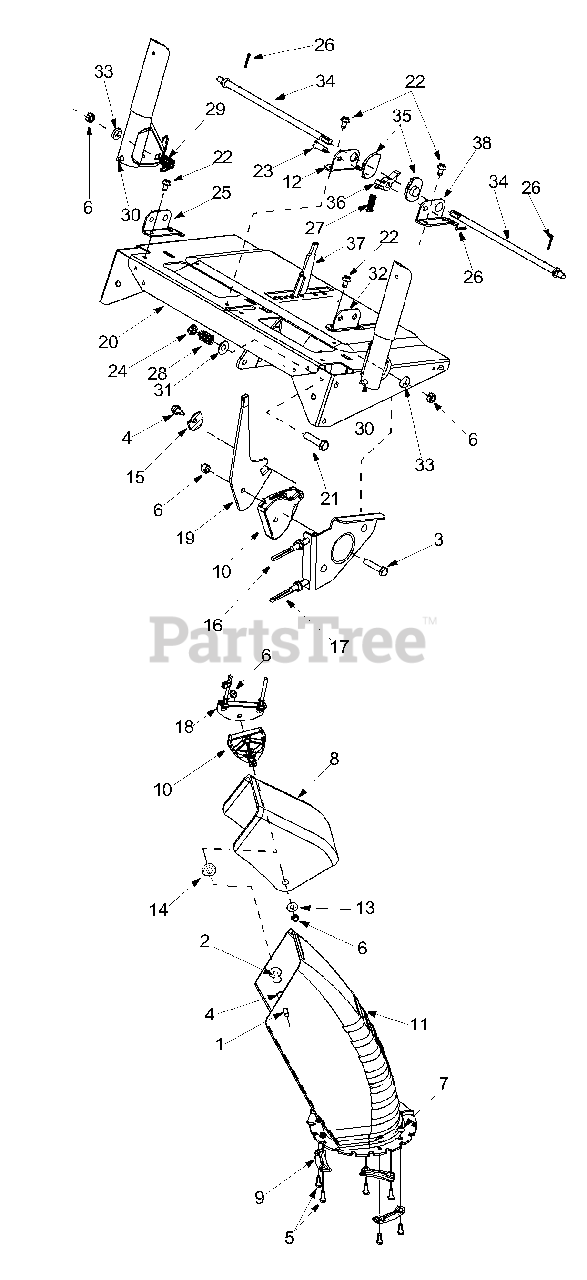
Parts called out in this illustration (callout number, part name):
1	Carriage Screw
2	Carriage Bolt 5/16-18 x 1.75"
3	Hex Bolt 5/16-18 x 1.5"
4	Hex AB Screw 1/4-14 x .625"
5	Hex Screw 1/4-20 x .75"
6	Hex Lock Nut
7	Hex Flange Lock Nut
8	Upper Chute
9	Chute Flange Keeper
10	Cable Guide, Chute Tilt
11	Lower Chute
13	5/16 Washer
14	Flat Washer
15	Special Washer
16	Chute Control Cable
17	Chute Cable w/Clip
21	Hex Bolt 3/8-24 x 1.5"
22	TT Screw 1/4-20 x 0.5"
23	Clevis Pin
26	Cotter Pin
29	Torsion Spring
30	Rubber Bumper
31	Bell Washer
33	Special Washer
35	Cam, Handle Lock
36	Pawl, Handle Lock
